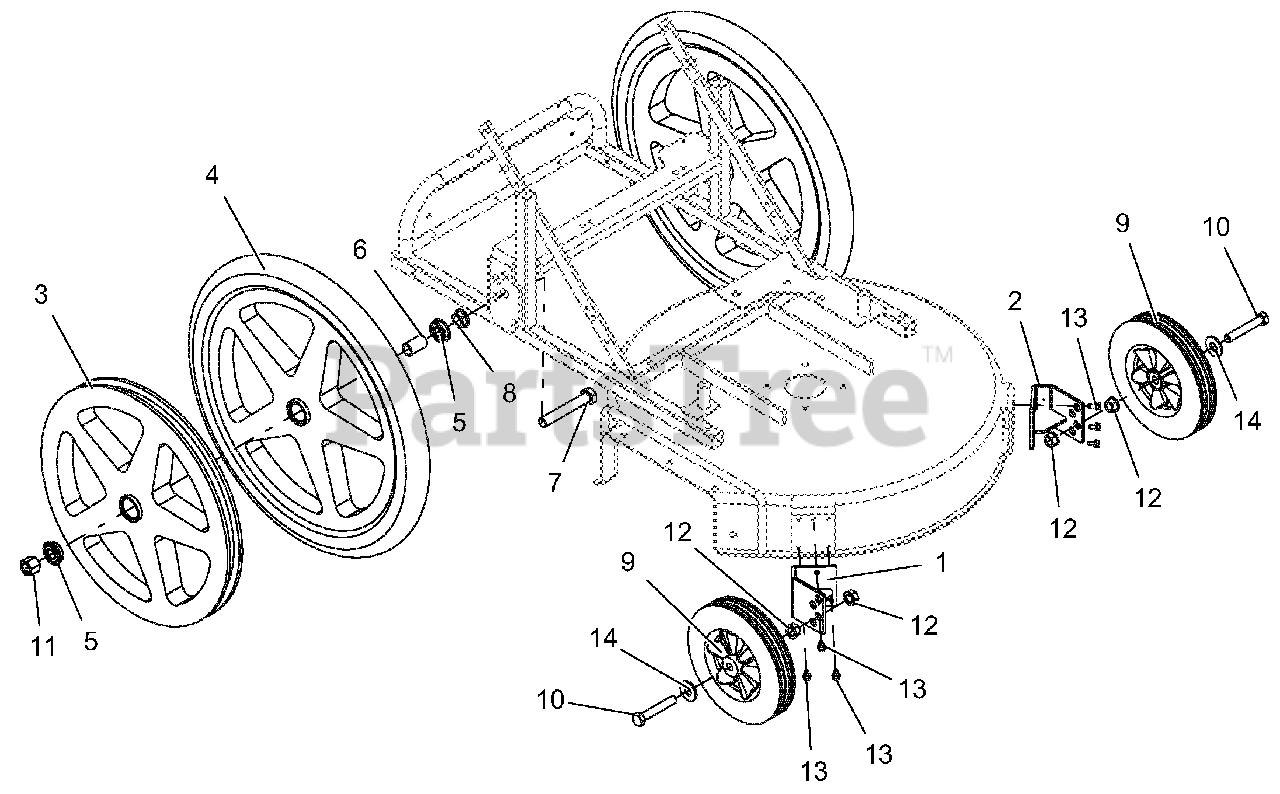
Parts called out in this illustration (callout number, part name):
1	WMT-FIXED FRNT WHL SUPPORT, LH
2	WMT-FIXED FRNT WHL SUPPORT, RH
3	WHEEL, 20" BLACK MAG
4	WHEEL,20"TIRE/RIM ASSY BLK/MAG
5	BALL BEARING 5/8 ID X 1-3/8OD
6	SPACER, .640X.840X1.39
7	BLT-HEX .62-11X4.00 GR5 FTH YZ
8	NUT-HEX FLANGE .62-11 GR5 YWZC
9	WHEEL, PLASTIC-8"X1.75" BLACK
10	@BLT-HEX .50-13X3.00 GR5 YWZC
11	@NUT-LK-NYL .625-11 YWZC
12	@NUT-LK-TOP-FLG .50-13 YWZC
13	SCR-TAP .25-20X.50 HWH TR YWZ
14	@WSHR-FL-STL.563X1.38X.109YWZC
